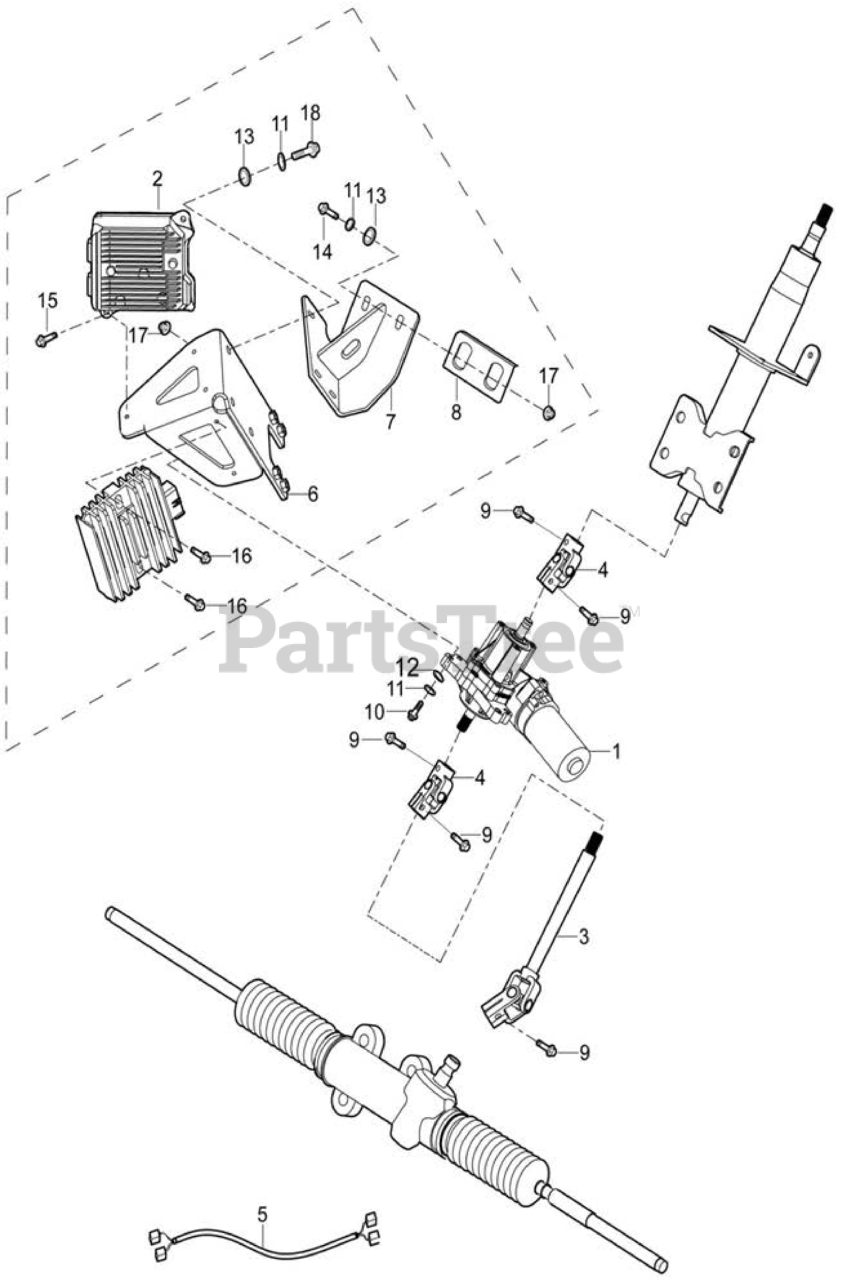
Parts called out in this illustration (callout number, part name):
1	Electrical Power steering Comp
2	EPS Controller
3	Transmisstion shaft
4	Steering Universal Joint
5	EPS Power Cable
6	EPS steering braket II
7	EPS steering braket I
8	EPS steering block
9	Flange Bolt M8X25
10	Flange Bolt M8X35
11	Spring Washer 8
12	Flat Washer 8
13	Flat Washer 8
14	Flange Bolt M8X65
15	Flange Bolt M8X30
16	Flange Bolt M8X20
17	Lock Nut M8
18	Flange Bolt M8X25
